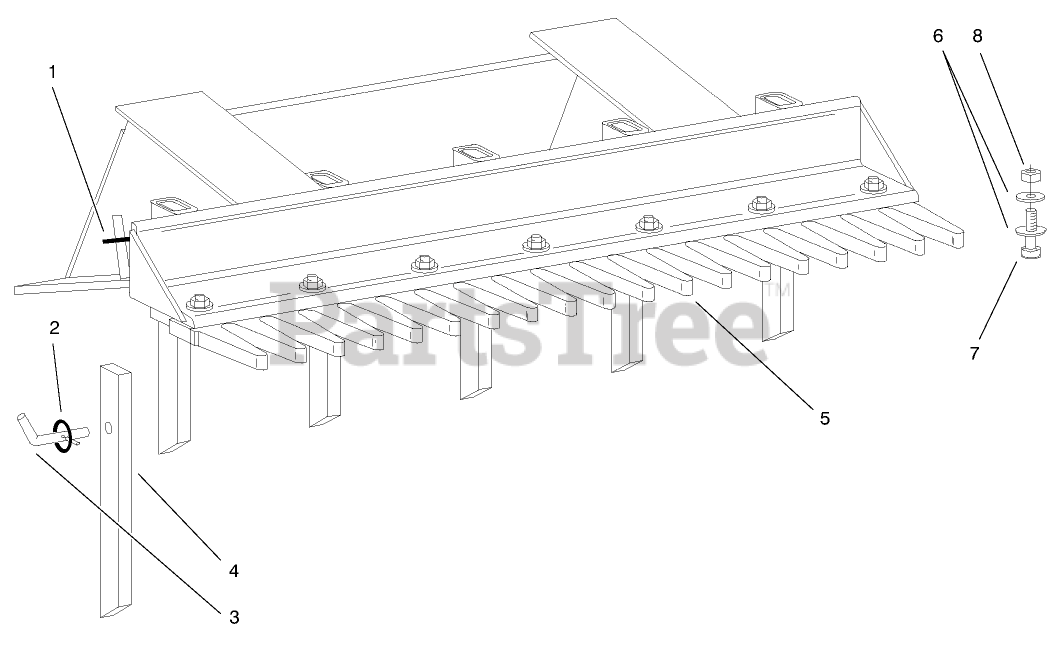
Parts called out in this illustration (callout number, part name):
1	PIN - STORAGE
2	PIN - LYNCH
3	ASSEMBLY - PIN
4	TOOTH
5	COMB - LEVELING
6	WASHER-FLAT
7	SCREW-HH
8	NUT-LOCK, NI
